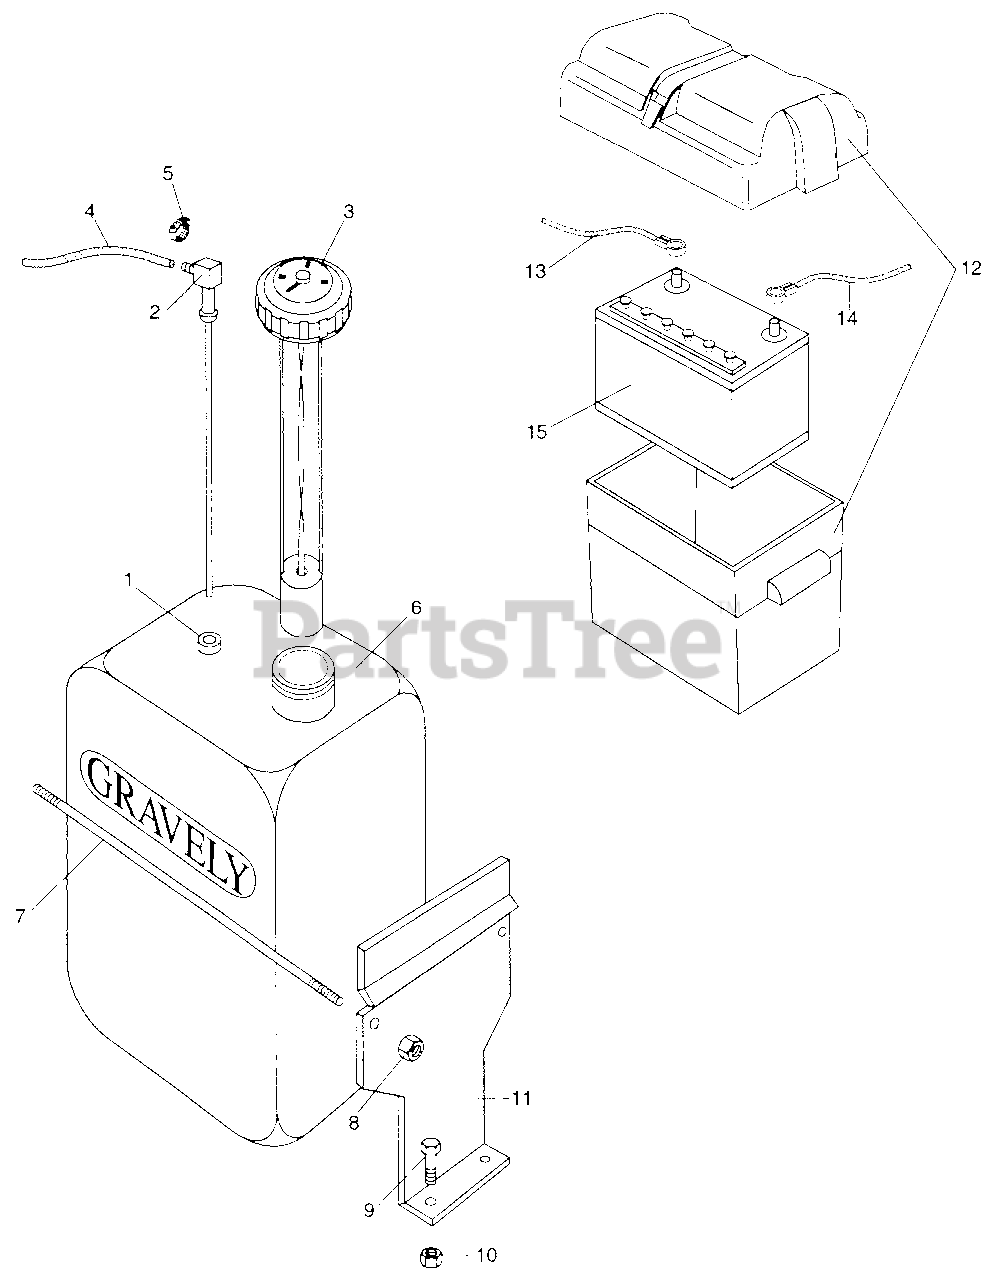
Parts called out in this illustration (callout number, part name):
1	BUSHING
2	FTG, TANK
3	GA, FUEL
4	GAS LINE - BULK
5	HOSE CLAMP
6	TANK, FUEL
7	ROD, TANK
8	NUT-LK-NYL .250-20 PL
9	BLT-HEX .31-18X.88 PL GR 5
10	NUT-LK-NYL .312-18 PL
11	WLDMT, TANK BRACKET
12	BATTERY BOX,(COVER & STRAP)
13	BATTERY CABLE(-)
14	BATTERY CABLE(+)
15	BATTERY MARINE TYPE
